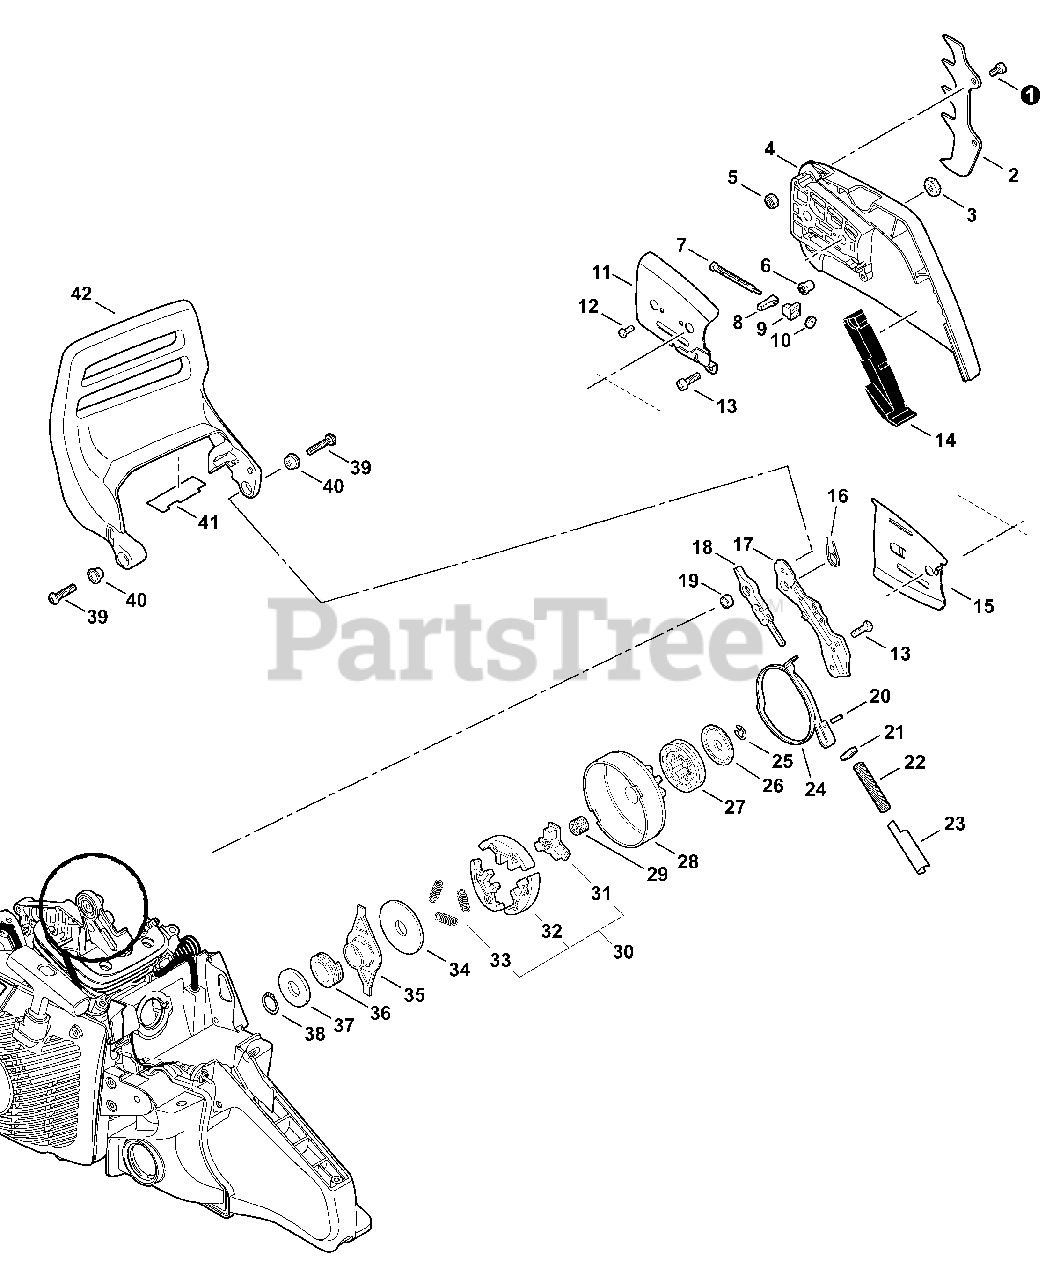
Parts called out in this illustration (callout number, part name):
1	BOLT, TORX 5
4	GUARD, SPROCKET
5	NUT, LOCK 5
6	GEAR,BEVEL
7	SCREW, TENSIONER - 63 MM
8	TENSIONER, CHAIN
9	GEAR,BEVEL
10	COLLAR,8
11	PLATE,SPROCKET GUARD
13	BOLT, TORX 4
14	PAD, GUARD
15	PLATE,SPROCKET GUARD
16	SPRING,TORSION
17	COVER,BRAKE
18	CONNECTOR, BRAKE
19	COLLAR,10
22	SPRING,COMPRESSION
23	PLATE, SIDE
24	BAND, BRAKE
26	WASHER,CIRCULAR 10
27	SPROCKET, RIM 68210S
28	DRUM, CLUTCH
29	BEARING,NEEDLE 10
30	CLUTCH ASY
31	HUB, CLUTCH
32	CLUTCH SHOE SET
33	SPRING,TENSION
34	PLATE, CLUTCH
35	COLLAR,14
36	GEAR,WORM
37	WASHER,CIRCULAR 16-1
38	CIRCLIP 15
39	BOLT, TORX 5
40	COLLAR,10
41	WASHER,SQUARE
42	LEVER, BRAKE
